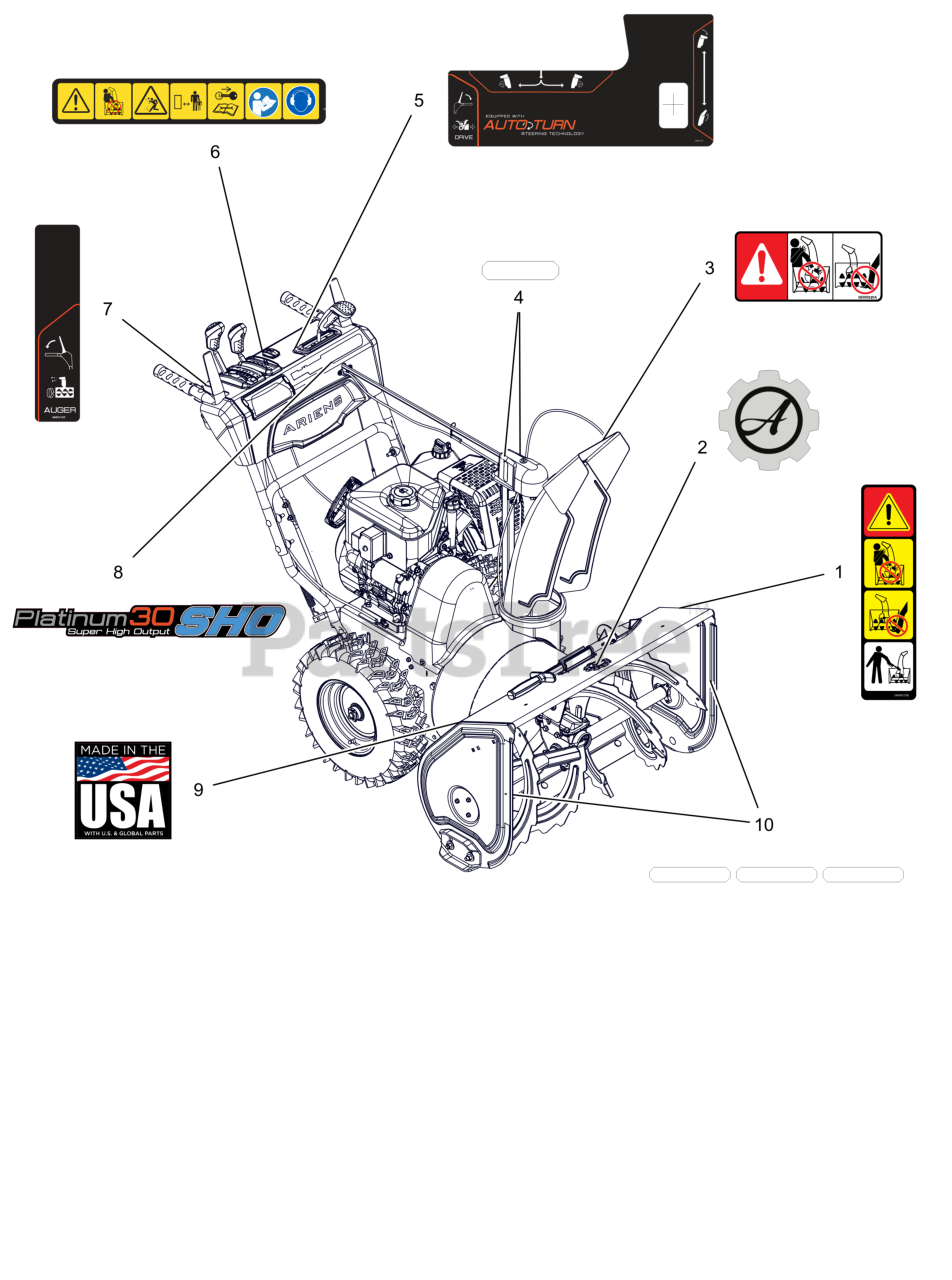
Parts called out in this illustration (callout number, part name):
1	DECAL, DANGER - ROTATING PARTS
2	DECAL, ARIENS - GEAR BADGE
3	DECAL, DANGER
4	DECAL,REFLECTIVE,GEAR COVER
5	DECAL,CONTROL-LG QT2
6	DECAL,DASH - SAFETY
7	DECAL,CONTROL-RH CONTROL
8	DECAL, DASH, PLATINUM 30 SHO
9	DECAL, MADE IN USA
10	DECAL,REFLECTIVE,HOUSING
